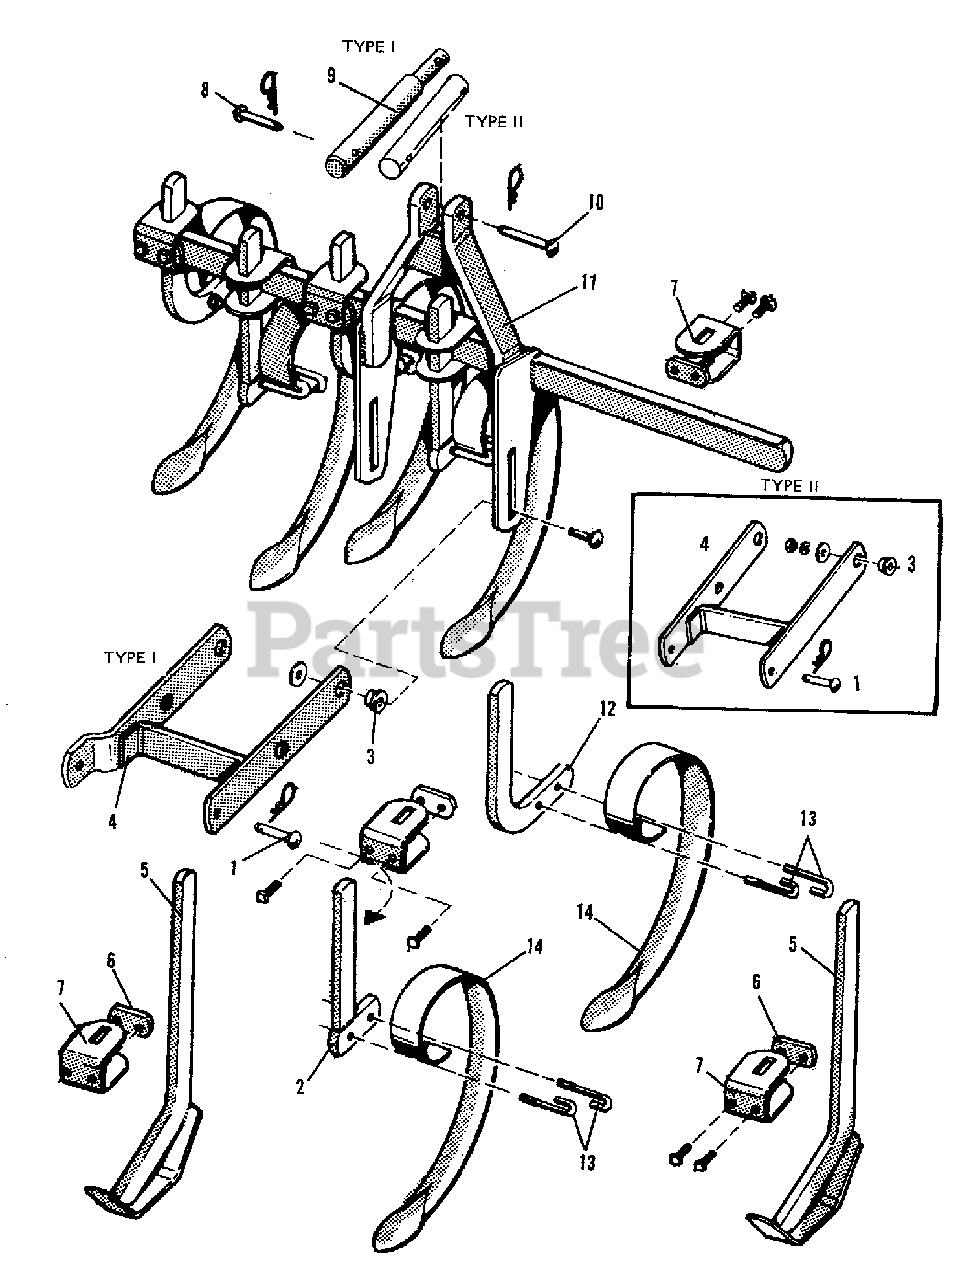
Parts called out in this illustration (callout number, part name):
1	PIN, Round Head
1	PIN, Quick
2	STANDARD ASSEMBLY, Straight
3	BOLT, Carriage, 7/16NC x 1-1/2
3	WASHER, 3/8
3	LOCKWASHER, 7/16
3	NUT, 7/16NC
4	ARM ASSEMBLY, Drawbar (Type I)
4	ARM ASSEMBLY, (Type II)
5	SHOW ASSEMBLY, Weld
6	NUT, Special
7	CLAMP, Shank
8	PIN, Quick
9	BAR, Lift (Type I)
9	*BAR, Lift (Type II)
10	PIN, Quick
11	BAR ASSEMBLY, Rear Tool (Shown)
12	STANDARD, Adjusting
13	BOLT, Spring Tooth
13	LOCKWASHER, 3/8
13	NUT, 3/8NC
14	TOOTH, Spring
